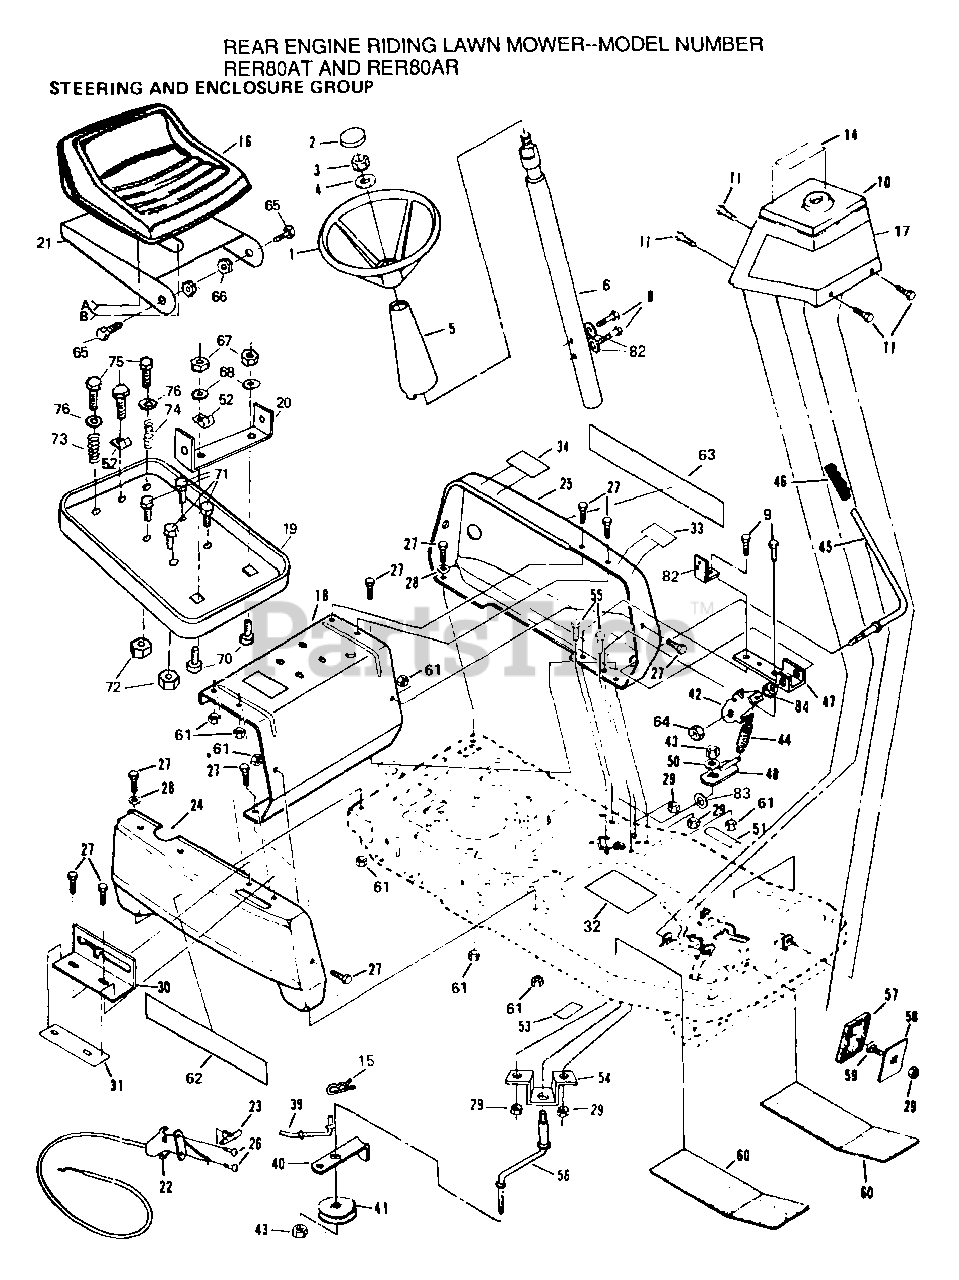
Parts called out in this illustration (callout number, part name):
2	INSERT CAP LT
3	NUT
9	BOLT
10	No Desciption for Part
11	SCREW LT
14	DECAL - OPERATING INSTRUCTIONS
15	SPRING.RETAINER
30	SHIFTER GATE T
31	DECAL SHIFT
33	DECAL - BLADE
34	DECAL - ENGINE
34	DECAL, ENGINE
39	BRAKE ROD RER
40	BELT KEEPER T
41	IDLER PULLEY T
45	LEVER.CLUTCH.BLAD
48	CONTROL ARM ASSY
52	CLIP LINE FUEL
54	IDLER SUPPORT BKT
55	BOLT
57	FOOT PAD LT
59	BOLT
62	DECAL - FENDER
63	DECAL - FENDER
64	LOCKNUT
68	WASHER
70	BOLT
75	SCREW
76	WASHER
82	LOCKWASHER
84	"NUT,KEPS"
